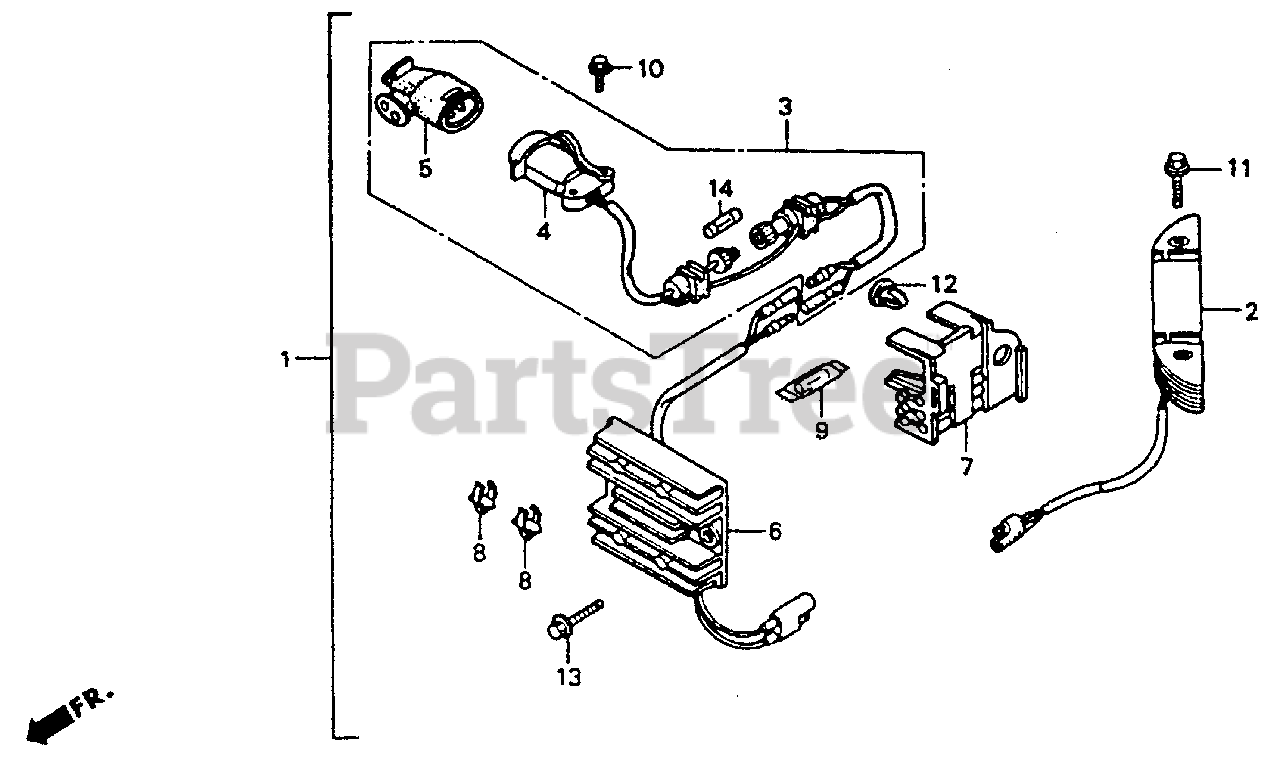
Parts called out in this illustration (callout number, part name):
1	RECEPTACLE KIT, LAMP
2	COIL ASSY., CHARGE (12V-6A)
3	RECEPTACLE ASSY., CHARGE
4	RECEPTACLE
5	PLUG, RECEPTACLE
6	RECTIFIER ASSY. (10A)
7	BRACKET, CONNECTOR (A)
8	CLIP, WIRE
9	FUSE, SPARE (15A)
10	BOLT, FLANGE (5X22)
11	BOLT, FLANGE (6X32)
12	CLIP, ANCHOR
13	BOLT, FLANGE (6X12)
14	FUSE A (15A)
